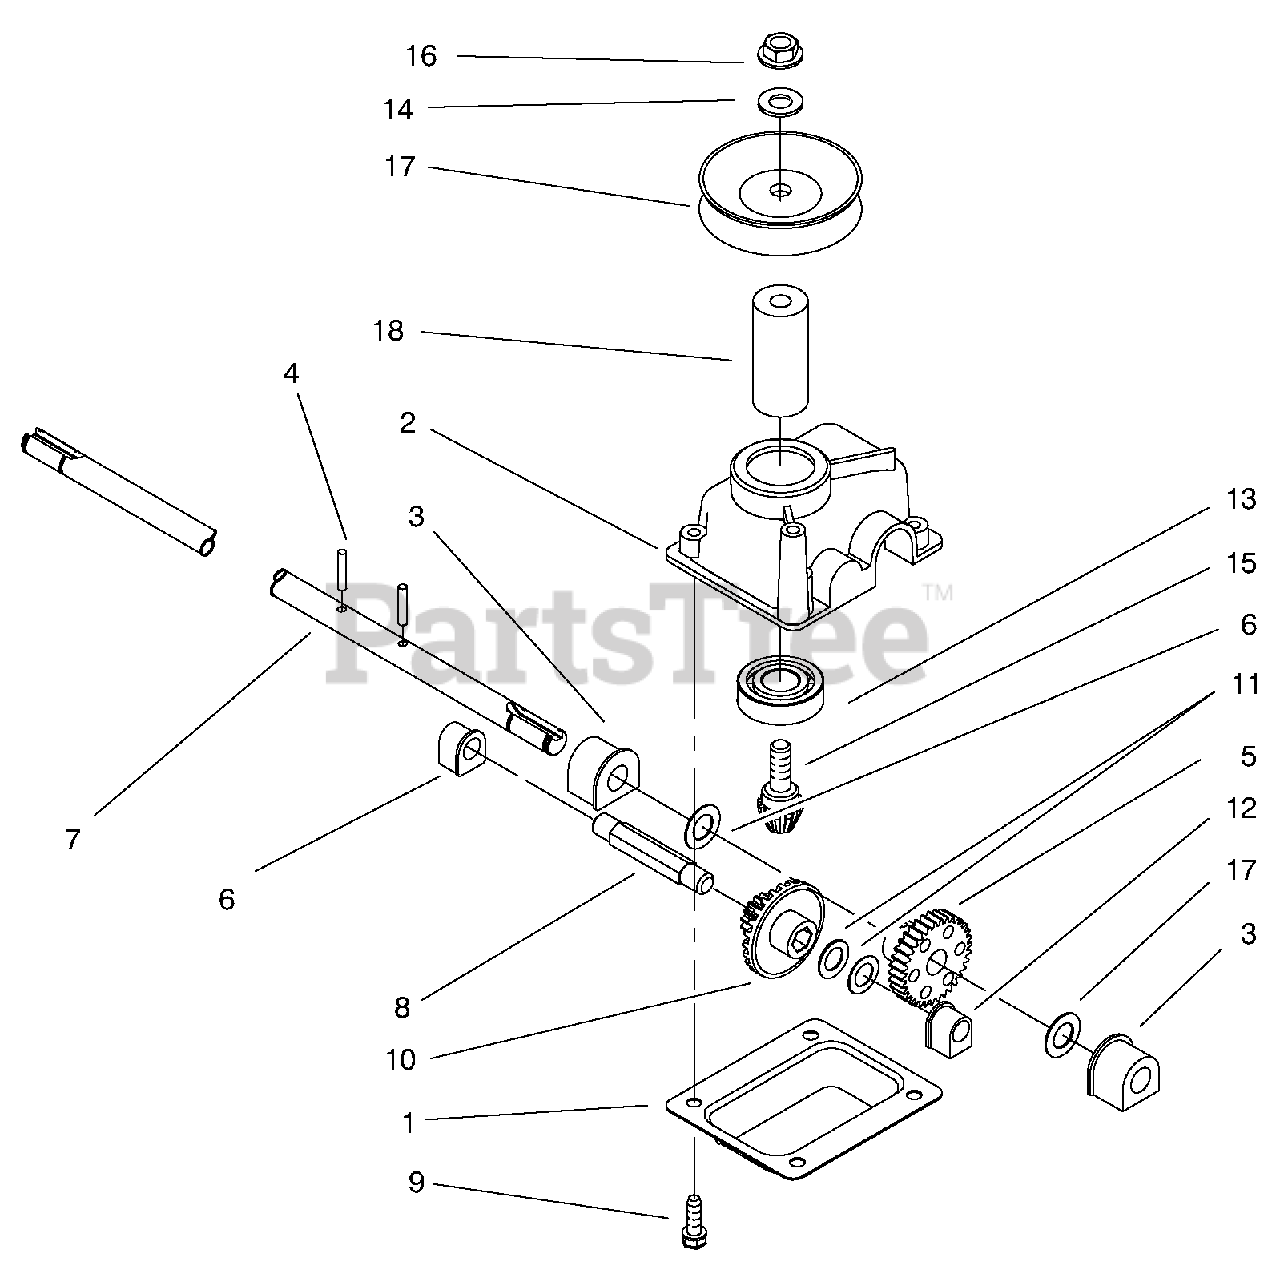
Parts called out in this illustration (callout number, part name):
1	Cover-Gear Case
2	Gearcase-Upper Ss
3	Bushing-Output
4	Pin-Spirol
5	Gear-34t
6	Washer-Thrust
7	Shaft-Output
8	Shaft-Intermediate
9	Screw-TAP
10	15 T Pinion
11	Washer-Thrust
13	Bearing-Ball
14	Washer-Flat
15	Gear-Pinnion
16	Nut-Lock
17	Pulley-Half
18	Spacer-pulley
